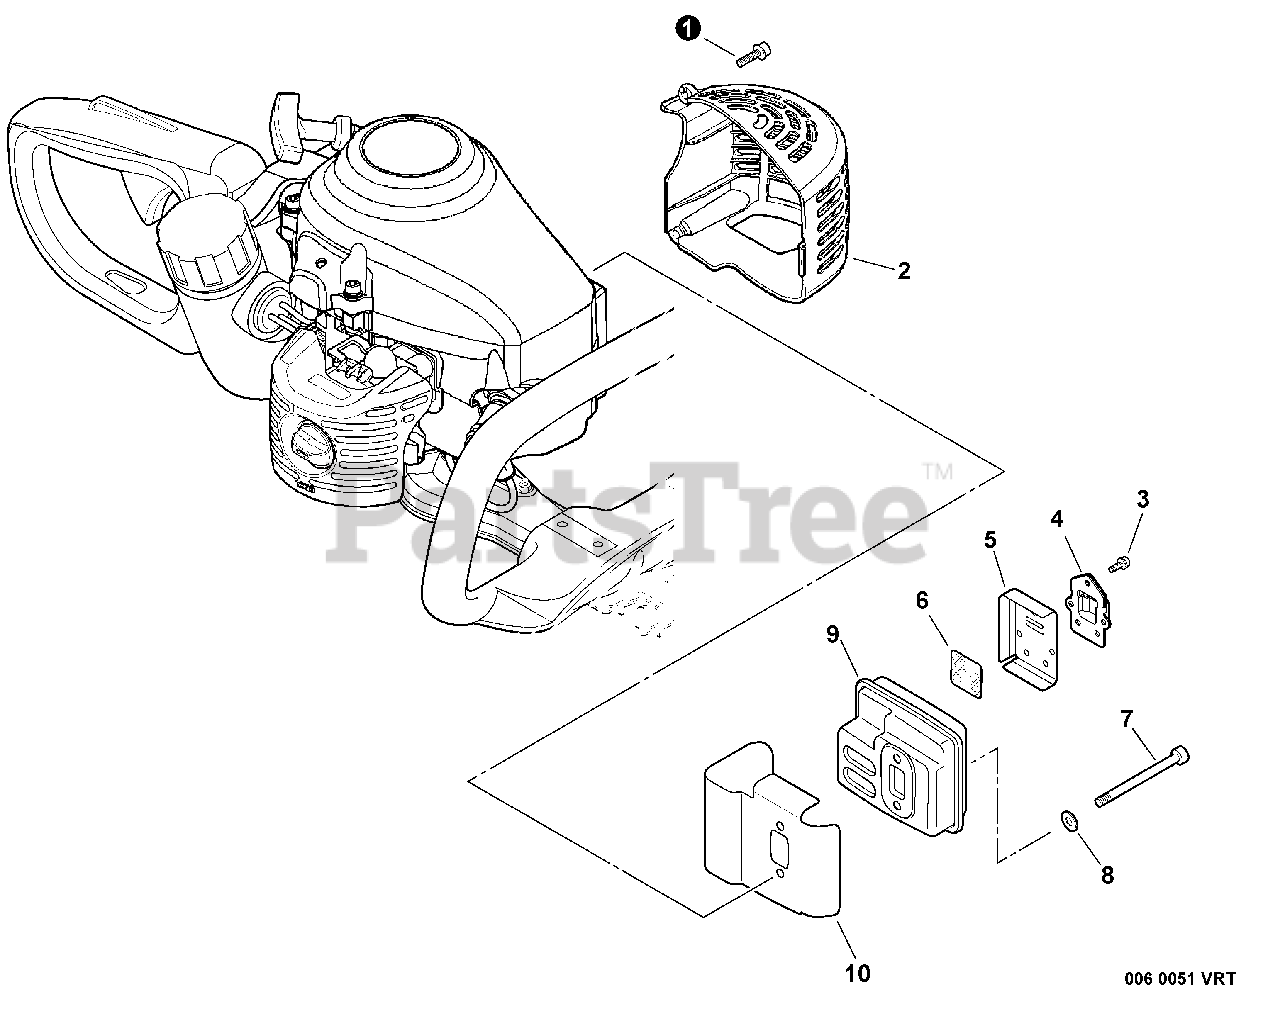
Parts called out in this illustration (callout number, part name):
1	BOLT 5×16
2	COVER, MUFFLER
3	SCREW 4×10
4	GUIDE, EXHAUST
5	GASKET, EXHAUST
6	SCREEN, SPARK ARRESTER
7	BOLT 5×55
8	WASHER, FLAT 5.5×10×0.8
10	HEAT SHIELD, EXHAUST
